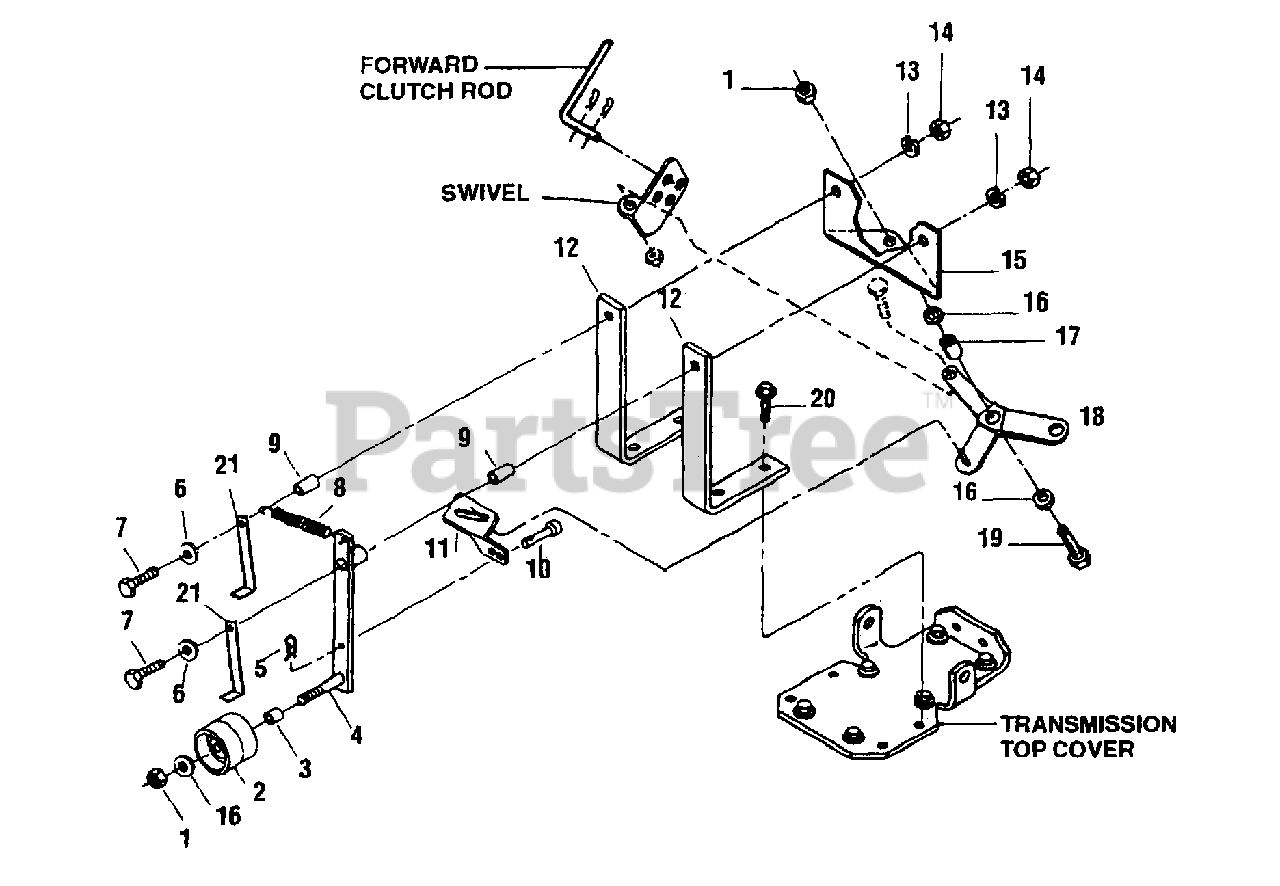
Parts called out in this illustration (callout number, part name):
1	Hex LOCknut, 3/8-16
2	Idler Pulley, Forward
3	Spacer
4	Left Idler Arm, forward tiller direction
5	Hairpin Cotter
6	Plain Washer. 5/16
7	Hex Hd. Screw, 5/16-18 x 2-1/4
8	Spring
9	Pivot Bushing
10	Pin
11	Forward Link
12	Mounting Bar
13	Lockwasher, 5/16
14	Hex Nut, 5/16-18
15	Shifting Base
16	Spacer (Bushing)
17	Bushing (Bellcrank)
19	Hex Hd. Screw, 3/8-16 x 1-1/4
20	Hex Flange Screw, 5/16-18 x 1
21	Belt Guide, Forward Belt
